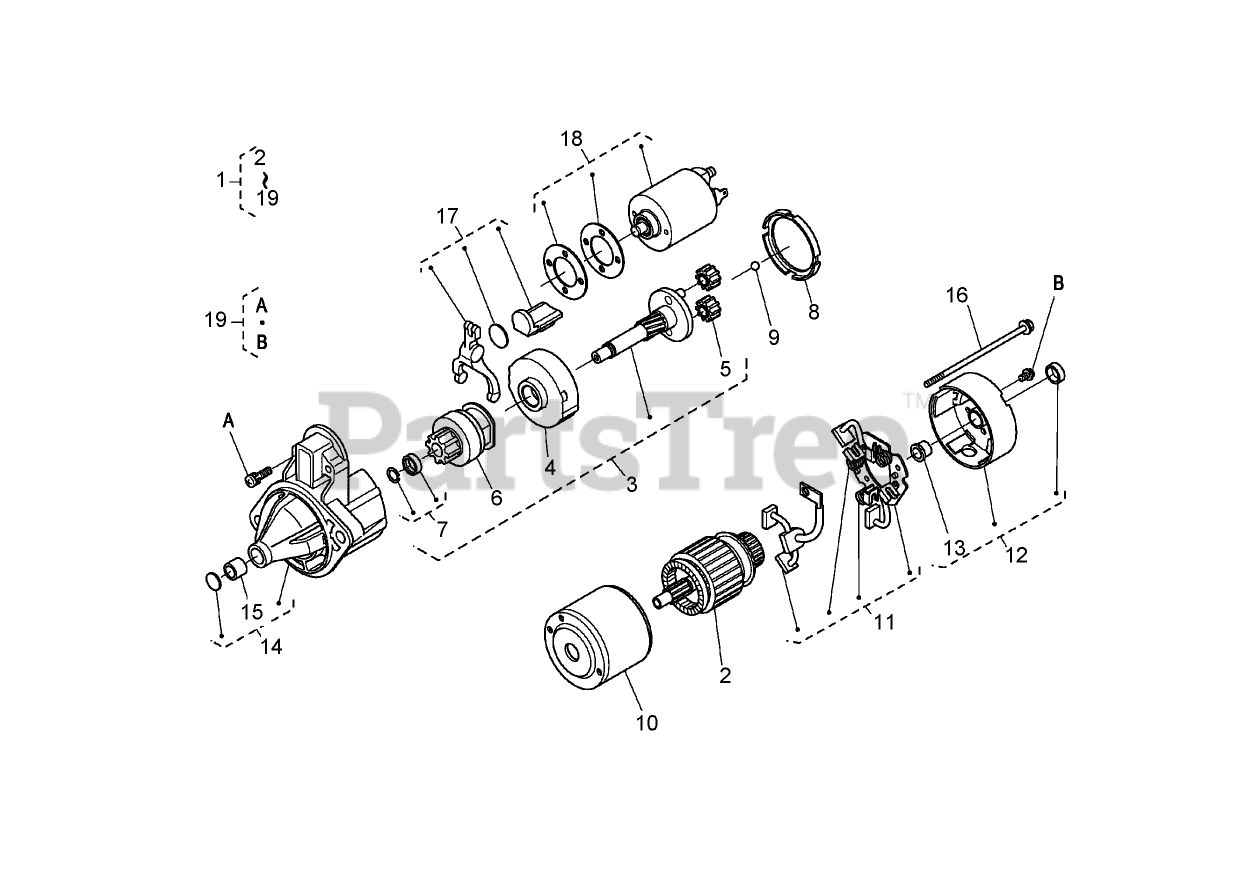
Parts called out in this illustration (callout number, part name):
1	STARTER ASM
2	ARMATURE
3	SHAFT ASM
4	GEAR-INTERNAL
5	GEAR-PLANETARY
6	CLUTCH-RUNNING, OVER
7	STOPPER
8	GASKET
11	BRUSH HOLDER ASM
12	REAR BRACKET ASM
13	BUSHING
14	FRONT BRACKET ASM
15	BUSHING
17	FORK LEVER ASM
18	MAGNETIC SWITCH ASM
19	SCREWS (SET OF 4)
